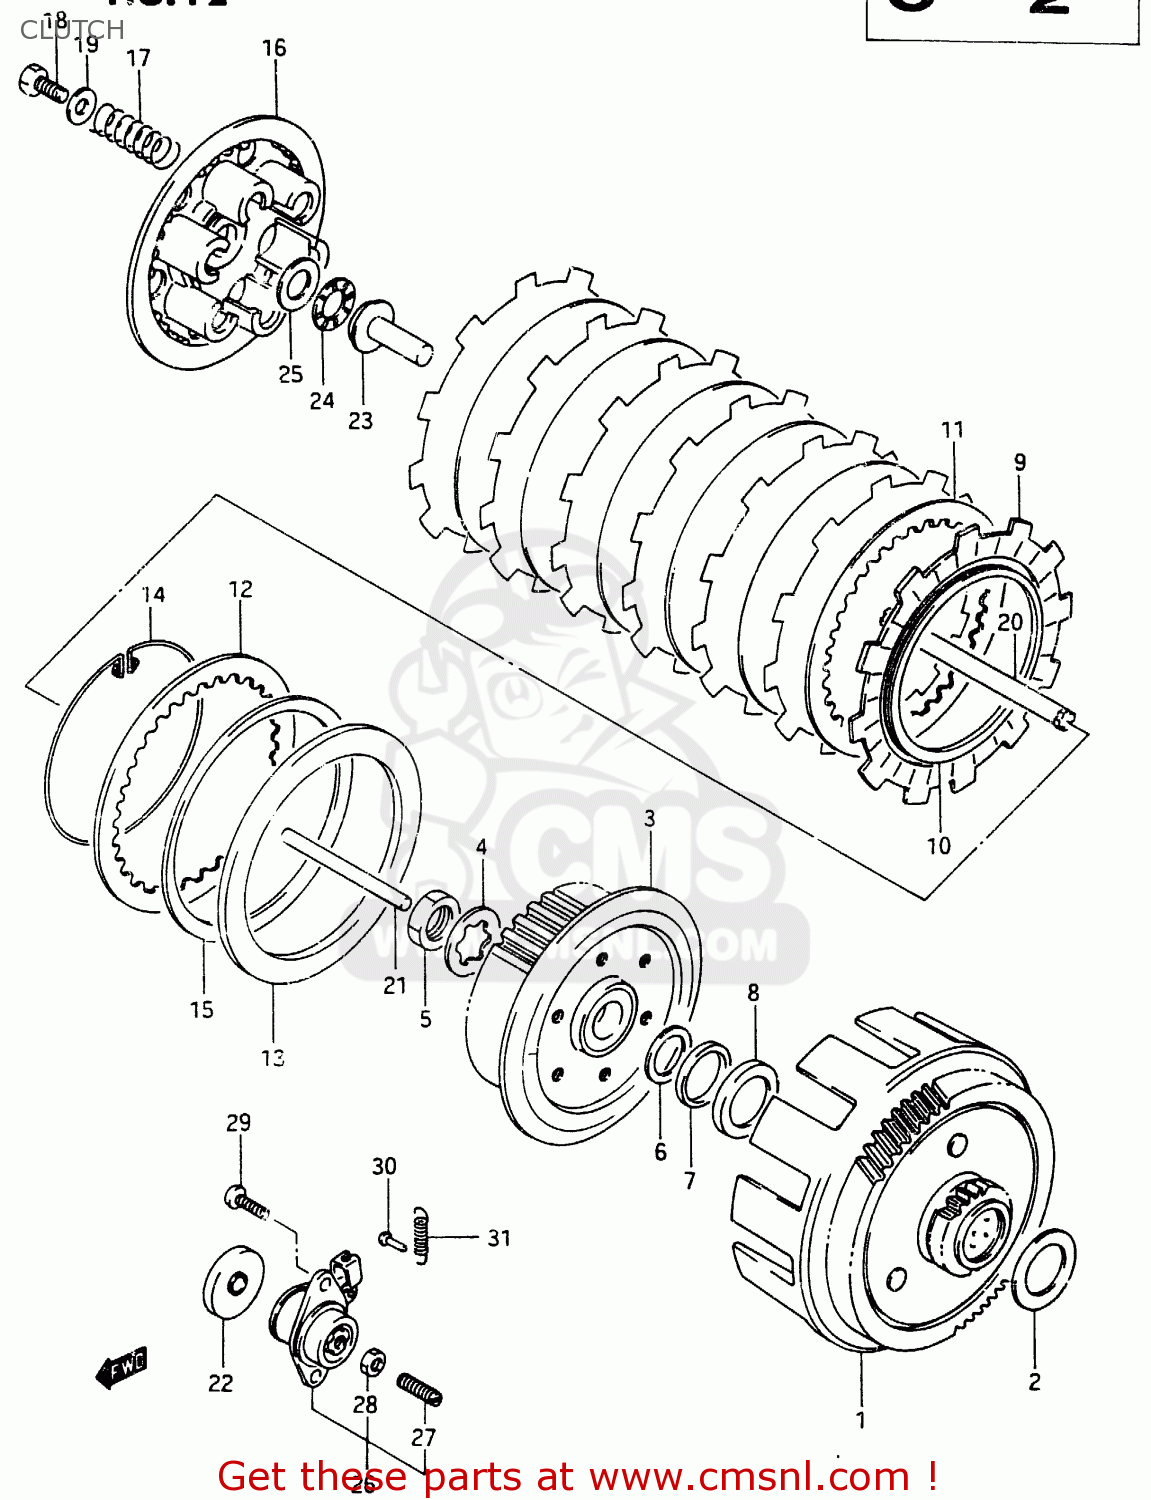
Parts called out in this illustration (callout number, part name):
1	GEAR ASSY, PRIMARY DRIVEN
2	WASHER
3	HUB,CLUTCH SLEEVE
4	WASHER,LOCK
5	NUT (20MM)
6	WASHER
7	WASHER (27X34X2)
8	WASHER
9	PLATE,CLUTCH (MCA)
10	V RING
11	PLATE, CLUTCH DRIVEN (T:1.6)
12	PLATE, CLUTCH DRIVEN (T:2.0)
13	SEAT,WAVE WASHER
14	RING,WAVE WASHER STOPPER
15	WASHER
16	DISC,CLUTCH PRESSURE
17	SPRING
18	BOLT
19	WASHER
20	ROD, CLUTCH PUSH
21	ROD, CLUTCH PUSH NO.1
22	SEAL,OIL(6X35X5.5)
23	PIECE,CLUTCH PUSH
24	BEARING(15X28X2)
25	WASHER
26	SCREW ASSY,CLUTCH RELEASE
27	SCREW(6X25)
28	NUT 6MM
29	SCREW 6X12
30	RIVET
31	SPRING
